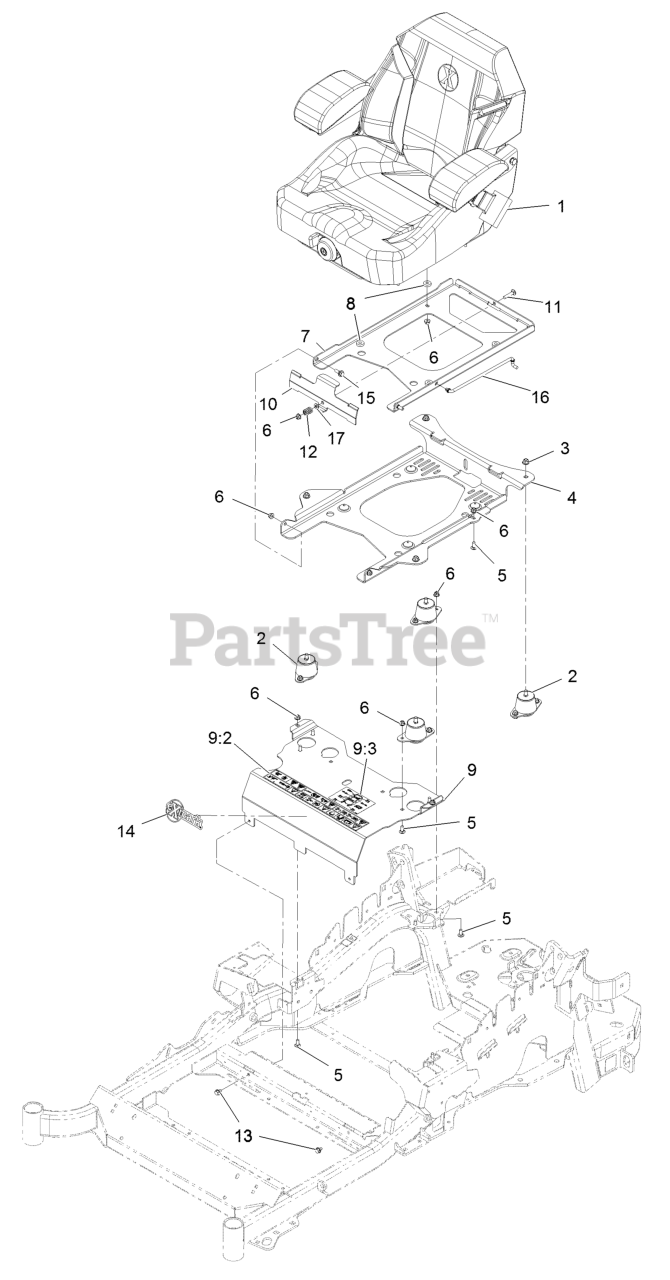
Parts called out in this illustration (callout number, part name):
1	KIT-SUSPENSION SEAT
2	ISOLATOR-SEAT
3	NUT-HF, NI
4	PLATE-TILT, SEAT SUPPORT
5	SCREW-CARR
6	NUT-HF, NI
7	PLATE-FRAME, SEAT
9	MOUNT-SEAT
9:2	DECAL-CONSOLE
9:3	DECAL-SERVICE AID
10	PLATE-LATCH, SEAT
11	BOLT-CARR
12	SPRING-COMPRESSION
15	SCREW-SHOULDER
16	ROD-PROP
17	WASHER-PLAIN
